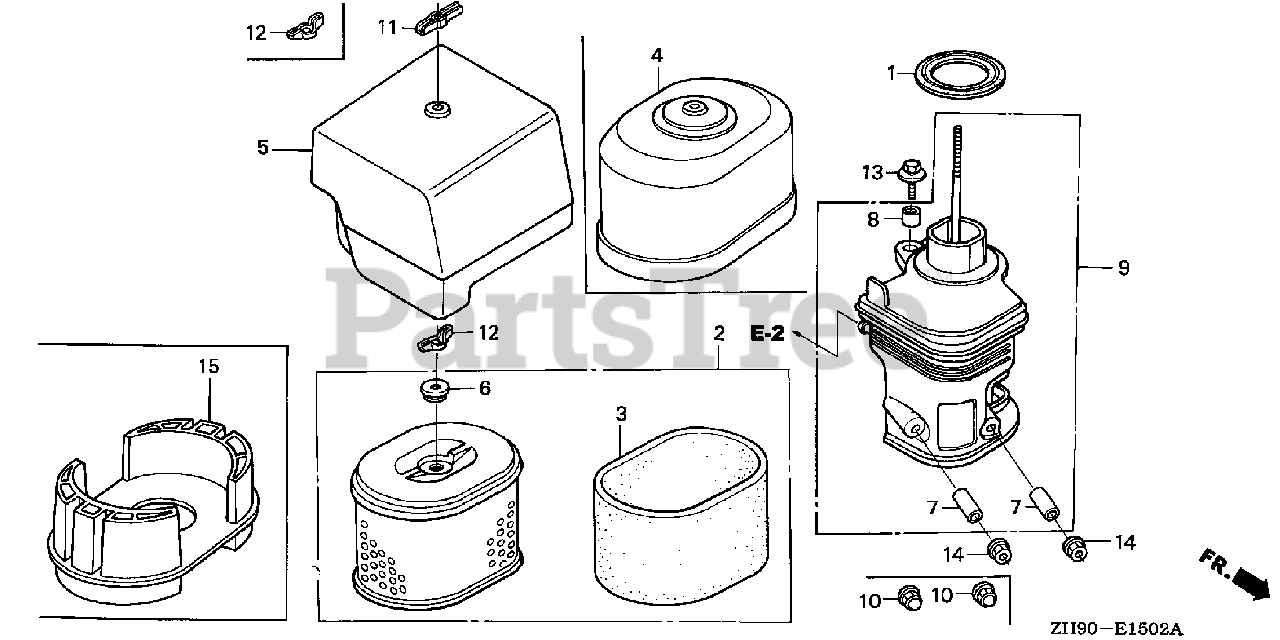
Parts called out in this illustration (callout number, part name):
1	GASKET, ELBOW
2	ELEMENT, AIR CLEANER (DUAL)
3	FILTER (OUTER)
5	COVER, AIR CLEANER
6	GROMMET, AIR CLEANER
7	COLLAR, AIR CLEANER
8	COLLAR B, AIR CLEANER
9	ELBOW, AIR CLEANER
12	WINGNUT, TOOL BOX SETTING
13	BOLT-WASHER (6X22)
14	NUT, FLANGE (6MM)
15	NOSE, MUFFLER
